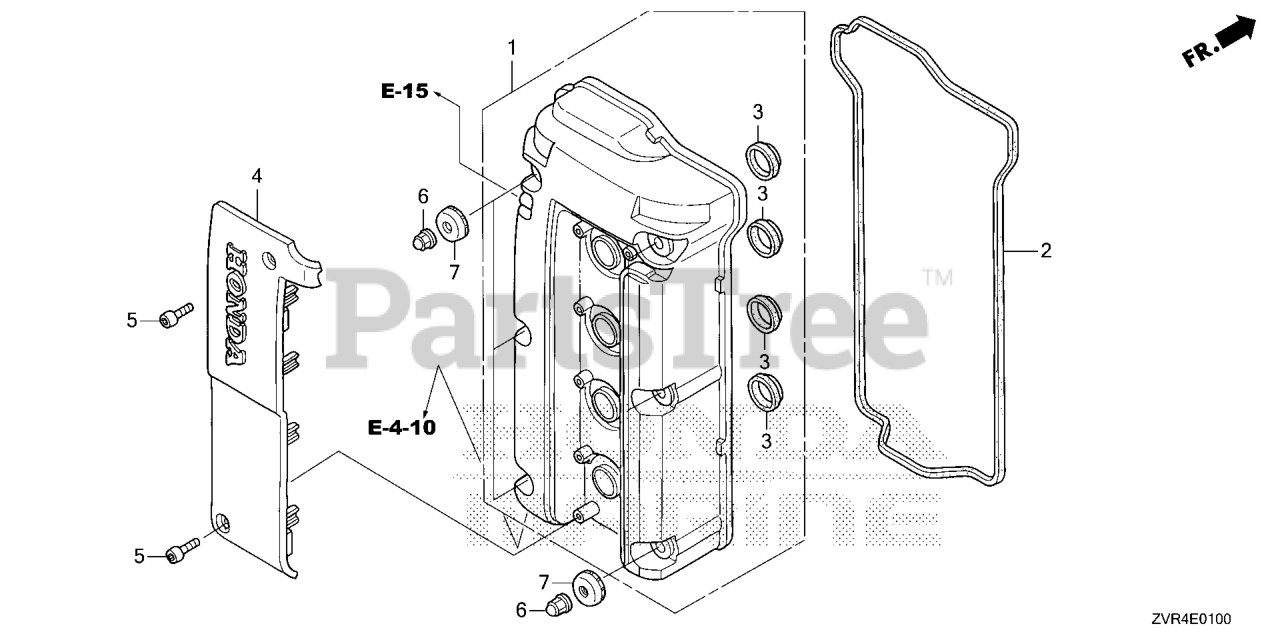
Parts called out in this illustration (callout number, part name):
1	COVER, CYLINDER HEAD *NH8* (DARK GRAY) (FOR 14540-RWC-A02)
2	GASKET, CYLINDER HEAD COVER
3	SEAL, SPARK PLUG TUBE (NOK)
4	COVER, PLUG HOLE COIL
5	BOLT, SOCKET (6X25)
7	WASHER, HEAD COVER
